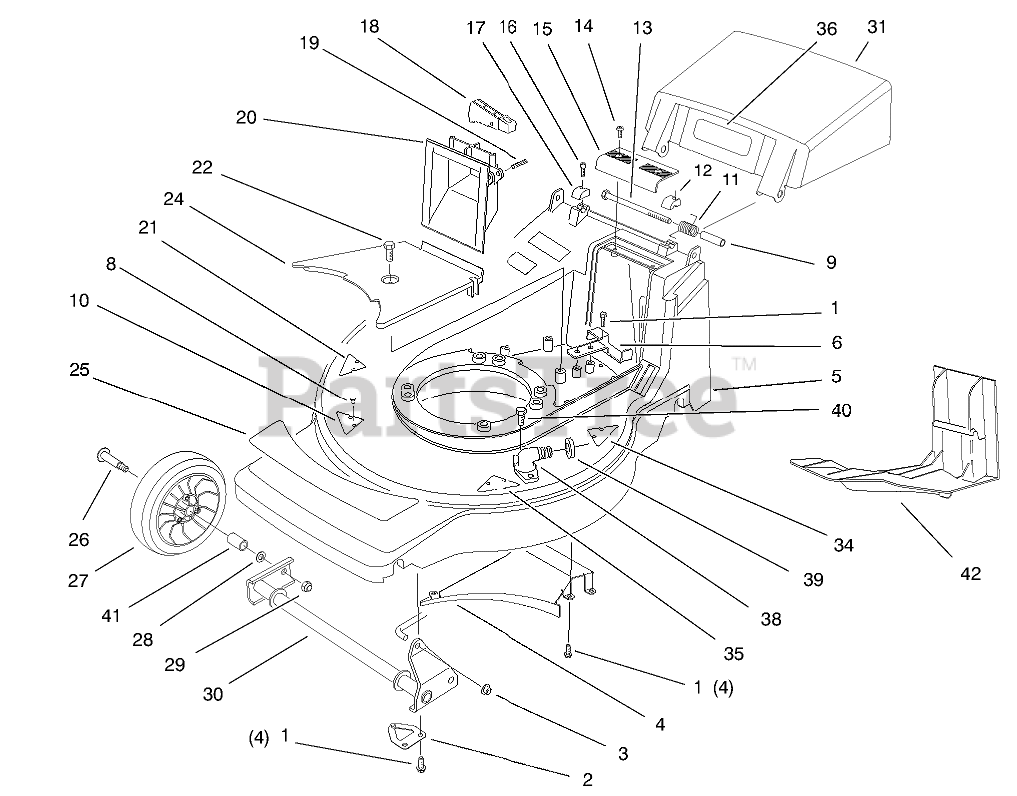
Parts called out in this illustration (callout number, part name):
1	SCREW-HWH
2	SHAFT RETAINER ASM
3	NUT-PUSH
4	Ramp-Discharge
5	Housing Assembly (Incl. Ref. # 8, 10, 21, 25, 1
6	REAR BELT GUIDE
8	SCREW-PPH
9	SPACER-DOOR
10	KICKER
11	SPRING-DOOR
12	CAP-HINGE BOLT, LH
13	SCREW-HH
14	SCREW-PPH, PLASTITE
15	GRIP-UPPER
16	SCREW-HSH
17	CAP-HINGE BOLT, RH
18	TRIGGER - HOC
19	PIN-SPIRAL
20	GRIP - LOWER
21	KICKER
22	SCREW-HWHTF
24	BELT COVER
25	DECAL - DECK
26	Bolt-Wheel
27	Wheel & Tire Assembly (Incl. Ref. #41)
28	WASHER
29	NUT-HEX
30	FRONT PIVOT WA
31	Discharge Door Assembly (Incl. Ref. # 36)
34	KICKER
35	KICKER
36	DECAL-DANGER
38	FITTING-WASHOUT
39	O-RING
40	SCREW-HWH
41	BUSHING
42	DISCHARGE PLUG
